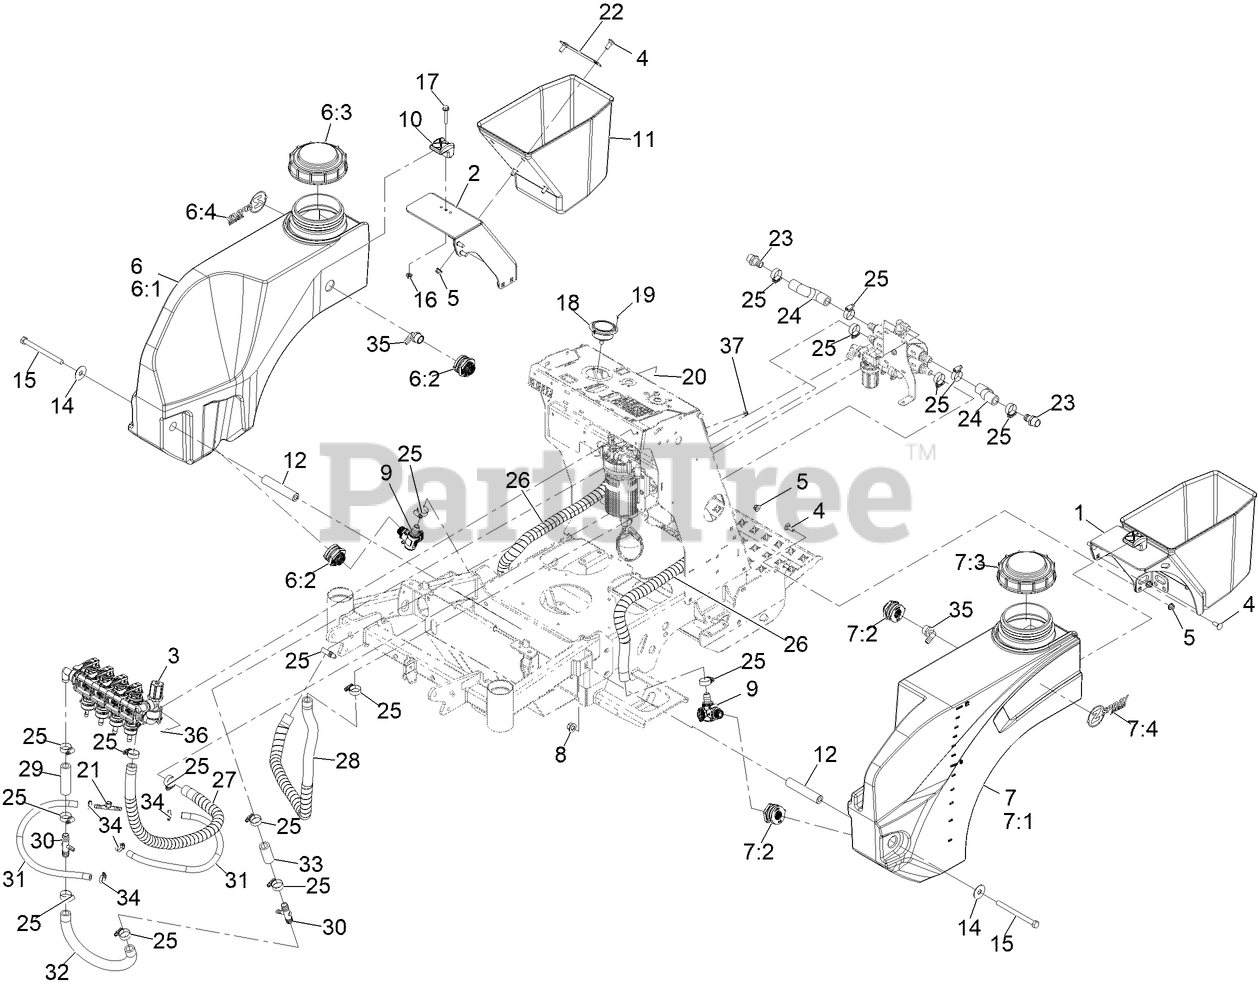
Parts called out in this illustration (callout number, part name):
1	FENDER-LT
2	FENDER-RT
3	ASM-MANIFOLD, SPRAY
4	SCREW-CARR
5	Nut-Hex Flange
6	TANK-12GAL, RT
6:1	Tank-12Gal, Rt
6:2	FITTING-BULKHEAD
6:3	CAP-TANK, SPRAY
6:4	DECAL-Z-SPRAY JUNIOR LOGO
7	TANK-12GAL, LT
7:1	Tank-12Gal, Lt
7:2	FITTING-BULKHEAD
7:3	CAP-TANK, SPRAY
7:4	DECAL-Z-SPRAY JUNIOR LOGO
8	NUT-HEX FLANGE
9	VALVE-3 WAY
11	BOX-FERTILZER, JR36
12	SPACER-TANK
14	WASHER-FLAT, 1/2, SS
15	HHCS,1/2-13X6 ST/ST,18-8
16	Nut-Hex Flange
17	SCREW-HHF
18	GAUGE-PRESSURE
19	SCR,MCH,6-32X3/8,PHPH,SST,ROHS
20	NUT-HEX
21	FITTING-TEE
22	PLATE-BACKING, FERT BOX
23	HOSEBARB
24	HOSE-RETURN
25	CLAMP-HOSE
26	HOSE-SPRAY, WRAPPED
27	HOSE-SPRAY, WRAPPED
28	Hose-Spray, Wrapped
29	HOSE-SPRAY
30	TEE-HOSE BARB
31	HOSE-SPRAY
32	Hose-Spray
33	HOSE-SPRAY
34	CLAMP-HOSE
35	FITTING-ELBOW, 90
36	Screw-HHF
37	Nut-Hex Flange
